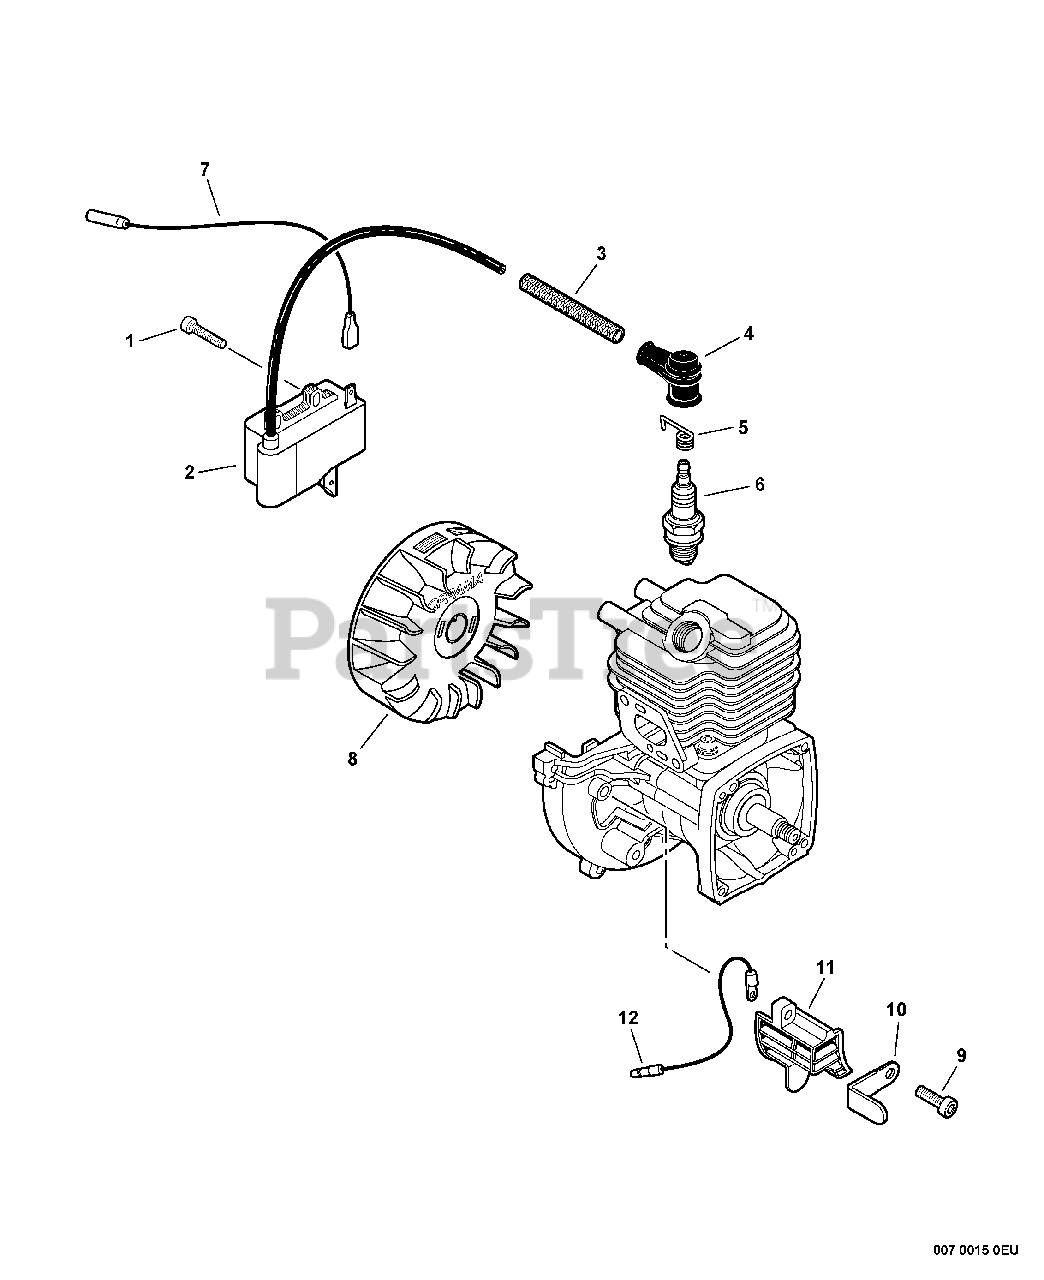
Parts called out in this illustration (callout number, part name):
1	SCREW - 4X20
2	COIL, IGNITION
3	TUBE, INSULATOR
4	CAP, SPARK PLUG
5	TERMINAL, SPARK PLUG CAP
6	SPARK PLUG -- BPMR-8Y
7	LEAD - IGNITION
8	FLYWHEEL
9	SCREW - 5X16
11	GUARD, DEBRIS
12	LEAD - GROUND
